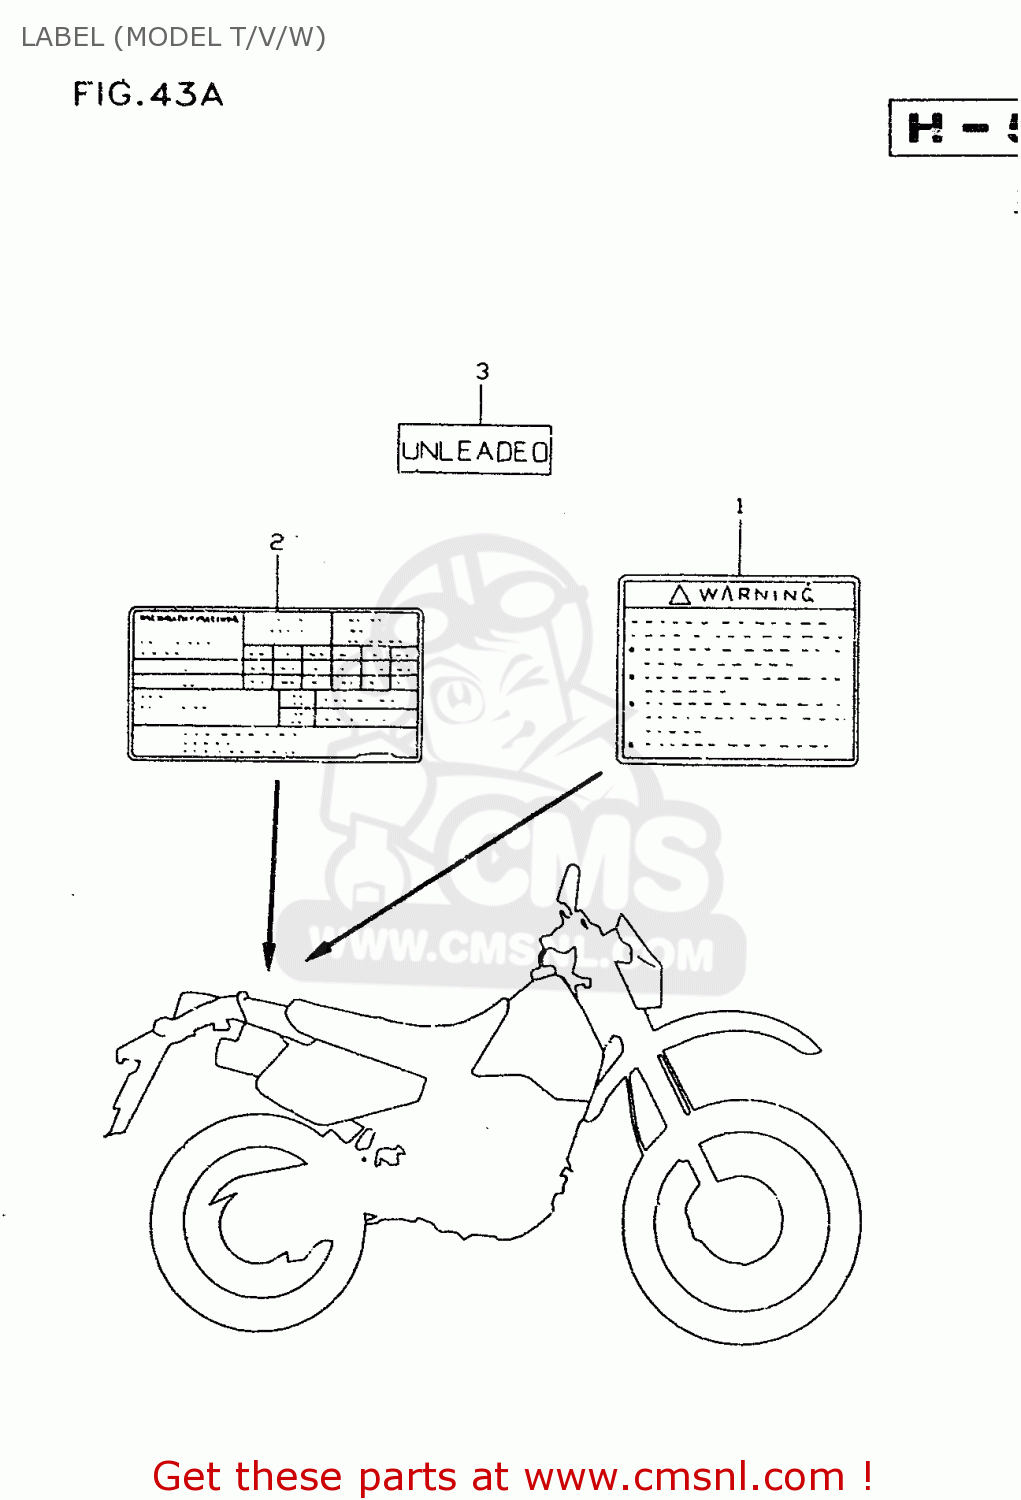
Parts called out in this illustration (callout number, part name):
1	LABEL,WARNING
2	LABEL, TIRE AIR PRESSURE
3	LABEL,CAUTION
4	MANUAL, OWNER'S
